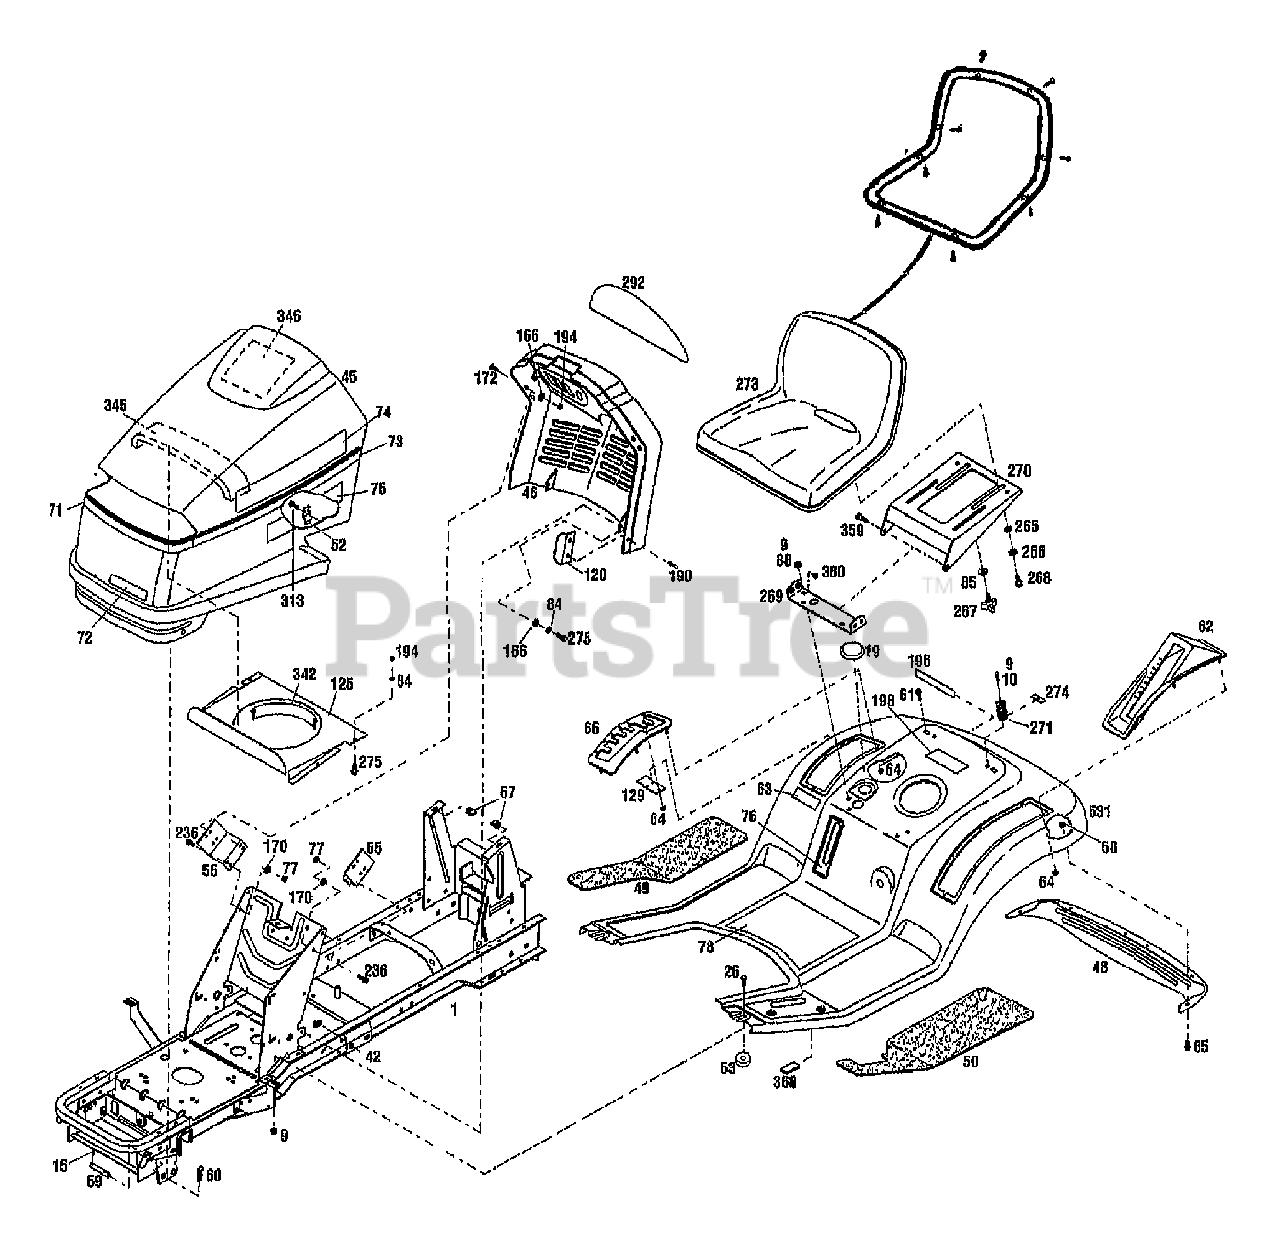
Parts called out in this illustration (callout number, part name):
9	NUT-HFLK 5/16-18 ZP
10	SCR-HHC 5/16-18X.75 GR 5 ZP
19	PLUG 2.50
26	SCR-CARR 5/16-18X1.0 G2 ZP
42	NUT-SPEED
45	HOOD-TRACTOR
46	CONSOLE
48	TRIM-FENDER REAR
49	PAD-FOOT RH
50	PAD-FOOT LH
52	LATCH
53	SPACER-TUBULAR
56	NUT-HF/LK 1/4-20 ZP
59	PIN-PIVOT HOOD
60	PIN-HITCH .125X2.56 ZP
61	SCR-LOCK
62	COVER-LIFT HANDLE
63	DECAL-AMERICAN LEGEND-LRG
64	NUT-SELF THRD 1/4
65	SCR-HH 1/4-20X.625
66	QUADRANT-SHIFT
71	DECAL-STRIPE HOOD FRONT
72	DECAL-LOGO
73	DECAL-STRIPE SIDE
74	DECAL-LOGO TROY-BILT
75	DECAL-MODEL 13053
76	DECAL-FUEL LEVEL
77	NUT-HEX 5/16-18 ZP
78	DECAL-OPER INST
84	WASHER-LK .25 ZP
85	WASHER-FLAT 3/8 SAE
88	SCR-CARR 5/16-18X.62 G2 ZP
115	PIN-ROLL .188X1.0
120	BRKT-HOOD ALIGN
125	SHIELD-HEAT UPPER
129	SUPPORT-SHIFT ARM
166	WASHER-FLAT 1.25X.28X.062 ZP
170	WASHER-LK .312 ZP
190	RIVET-POP
194	NUT-HEX 1/4-20 ZP
196	DECAL-LOGO FENDER
198	DECAL-FUEL
236	SCR-HFLK 5/16-18X.75 ZP
265	WASHER-1.06X.51X.09 NYLON
266	WASHER-BOW .74X.52X.01
268	SCR-SHLDR 3/8-16X.25 G5ZP
269	BRKT-SUPPORT SEAT
270	SUPPORT-SEAT
271	SPRING-COMPRESSION
273	KIT-SEAT (TRACTOR)
274	BRKT-SPRING HOLD DOWN
275	SCR-HH 1/4-20X.625 G5 ZP
292	LENS-INSTRMTS WARN LIGHTS
342	GASKET-HEAT SHIELD
345	STRIP-SEALING
346	DECAL-SERVICE
359	SCR-HH 3/8-16X.88 G5 ZP
360	NUT-H/LK 3/8-16
531	FENDER-RED W/DECALS
